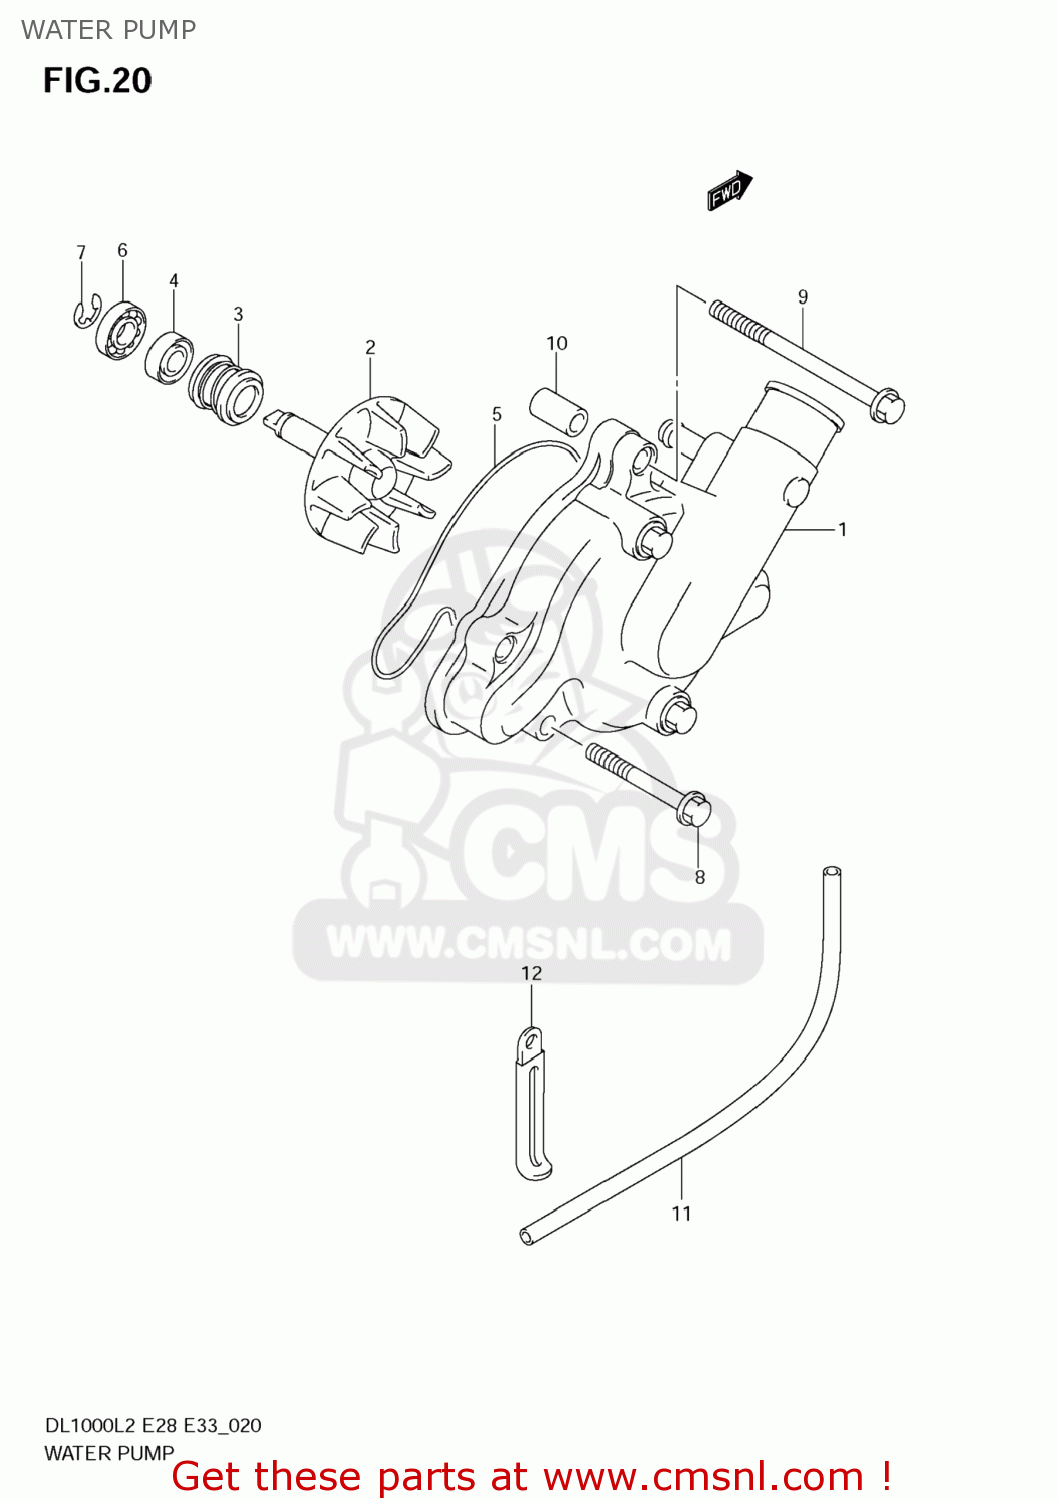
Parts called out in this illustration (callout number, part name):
1	CASE,WATER PUMP
2	IMPELLER,WATER PUMP
3	SEAL,MECHANICAL
4	SEAL,OIL(10X20X5)
5	O RING,WATER PUMP CASE
6	BEARING(10X22X5)
7	E RING
8	BOLT(6X30)
9	BOLT(6X65)
10	PIN
11	HOSE(4.2X7X600)
12	CLAMP(L:80)
